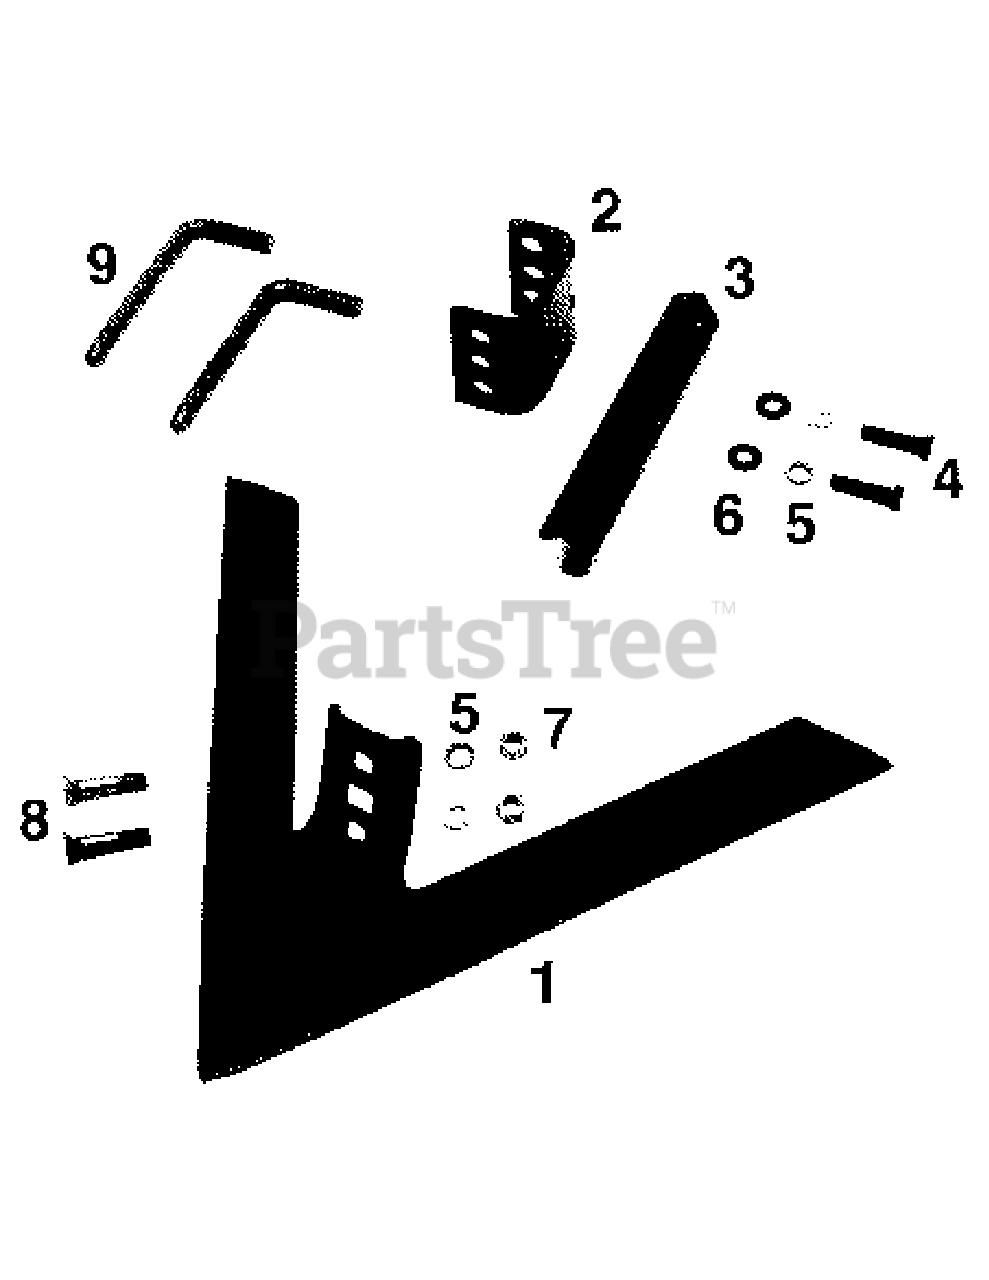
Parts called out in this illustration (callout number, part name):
1	Sweep with Flanged Stem
2	C-shaped Mounting Bracket
3	Channel Mounting Bracket
4	Hex Hd. Bolt, 7/16"-14 x 1-3/4"
5	Lockwasher, 7/16"
6	Flat Washer, 7/16"
7	Hex Nut, 7/16"-14
8	Plow Bolt, 7/16" -14 x 2"
9	Pin, 5/8" dia. x 5-5/8"
